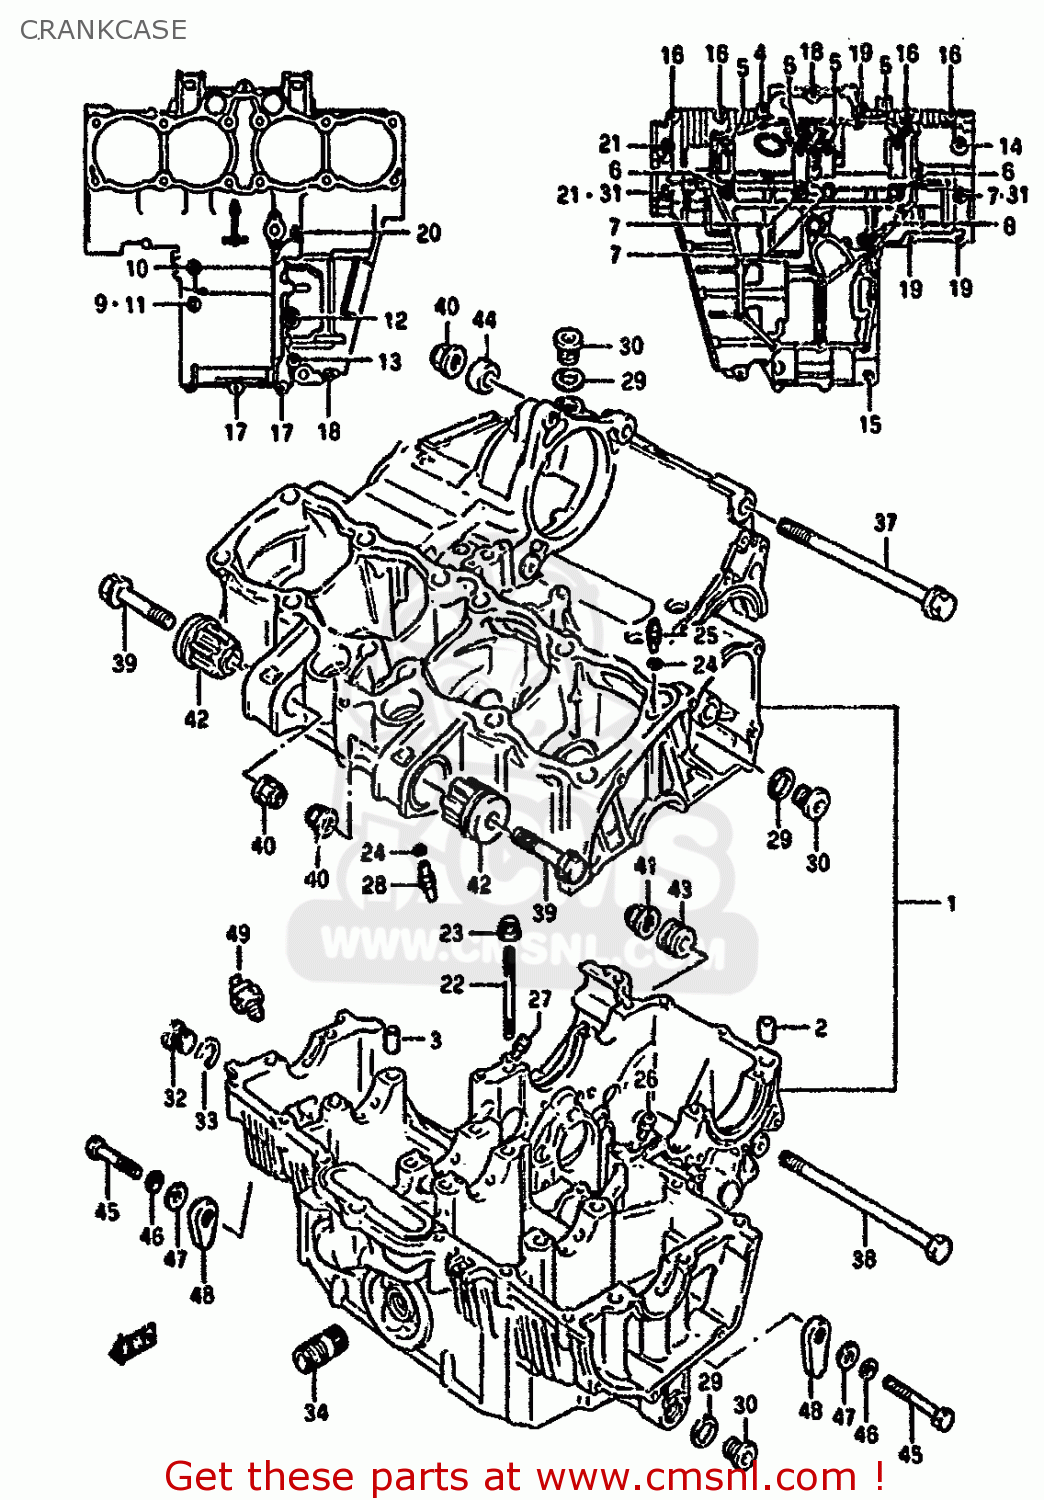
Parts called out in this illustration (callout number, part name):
1	CRANKCASE SET
2	PIN(10.4X13X22)
3	PIN (11X20)(SUS)
4	BOLT 6X100
5	BOLT 8X135
6	BOLT(8X145)
7	BOLT
8	BOLT(6X120)
9	GASKET(8.2X14X1) (NAS)
10	BOLT
11	BOLT
12	BOLT
13	BOLT
14	BOLT(8X85)
15	BOLT
16	BOLT
17	BOLT
18	BOLT (6X60)
19	BOLT
20	BOLT
21	BOLT(8X95)
22	STUD BOLT
23	NUT
24	O RING(D:1.2,ID:4)
25	JET,AIR
26	JET
27	JET(140)
28	JET
29	GASKET(16X22X2) (NAS)
30	PLUG
31	GASKET(8.5X17X2.3) (NAS)
32	PLUG,14X12
33	GASKET(14X19.2X2) (NAS)
34	UNION,OIL STAND
35	BEARING,CRANK THRUST(GREEN)
36	BEARING,CRANK THRUST(RED)
37	BOLT L:165
38	BOLT 12X151
39	BOLT
40	NUT (10MM)
41	NUT 12MM
42	BUSH,ENGINE MOUNTING
43	SPACER,ENGINE MOUNT
44	SPACER,ENGINE MOUNT
45	BOLT 10X70
46	WASHER
47	WASHER
48	NUT
49	SWITCH ASSEMBLY,OIL PRESSURE
